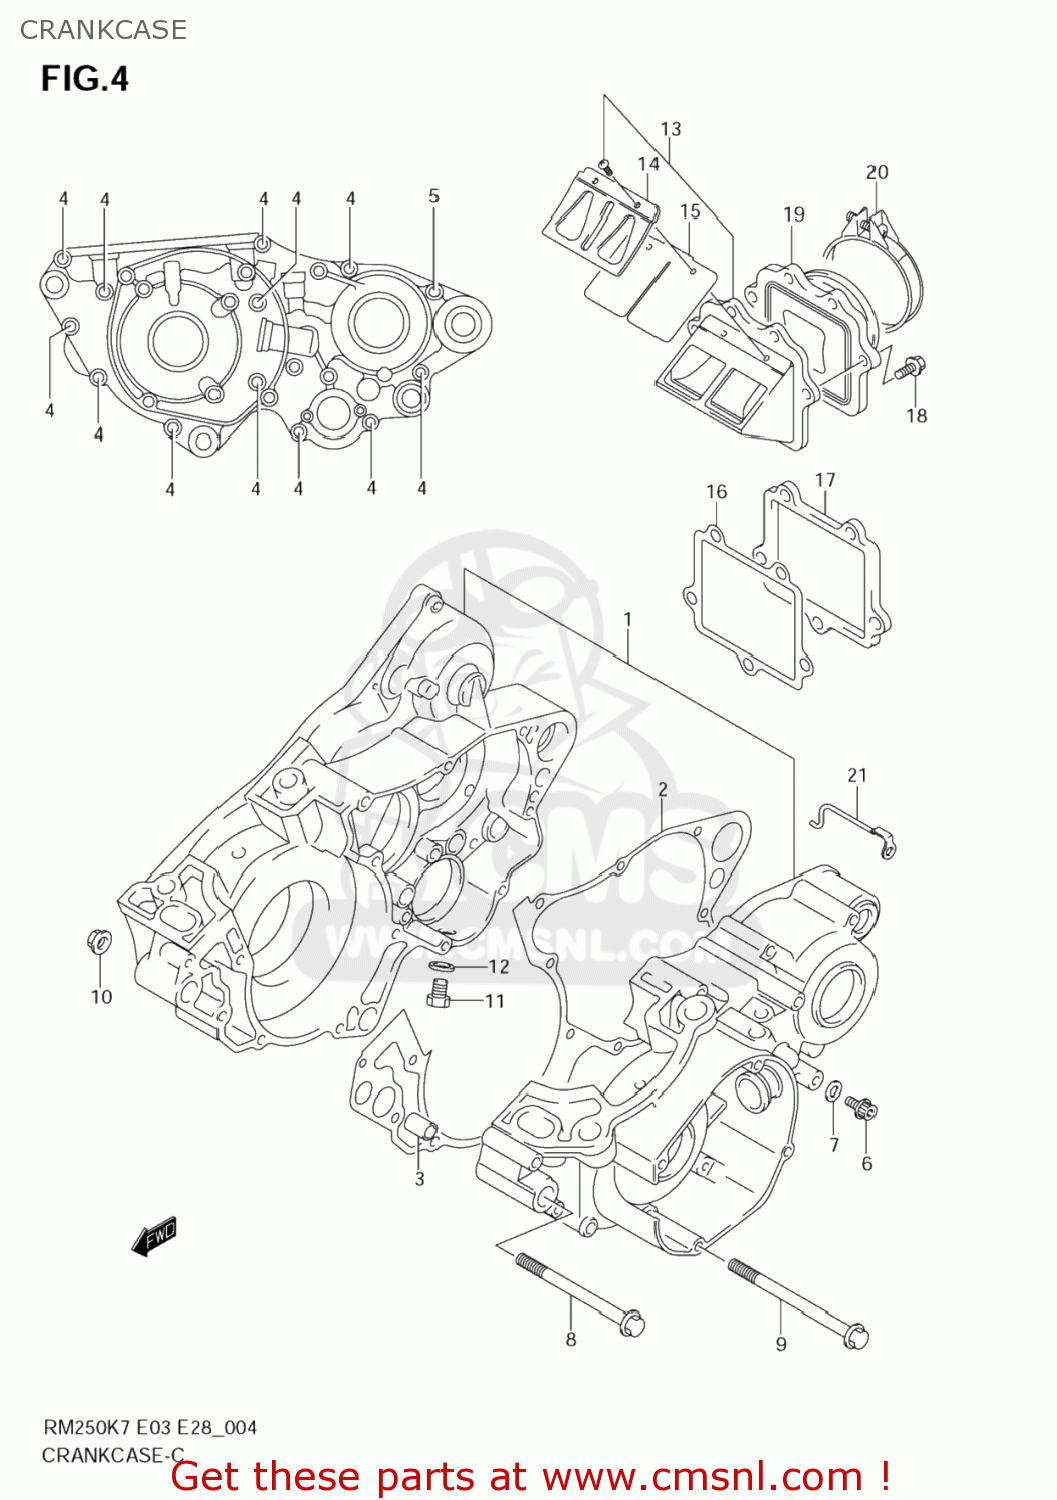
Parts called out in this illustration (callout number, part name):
1	CRANKCASE ASSY
2	GASKET,CRANKCASE (NAS)
3	PIN(13X10.4X20)
4	BOLT(6X50)
5	BOLT(6X65)
6	BOLT
7	GASKET(6.2X11X1).2 (NAS)
8	BOLT(10X105)
9	BOLT(10X125)
10	NUT
11	PLUG
12	GASKET(12.1X16.2X3.7) (NAS)
13	VALVE ASSY,REED
14	STOPPER,REED VALVE
15	VALVE,REED
16	GASKET,REED VALVE (NAS)
17	SPACER,REED VALVE
18	BOLT(6X25)
19	PIPE,INTAKE
20	CLAMP
21	GUIDE,CARBURETOR HOSE
